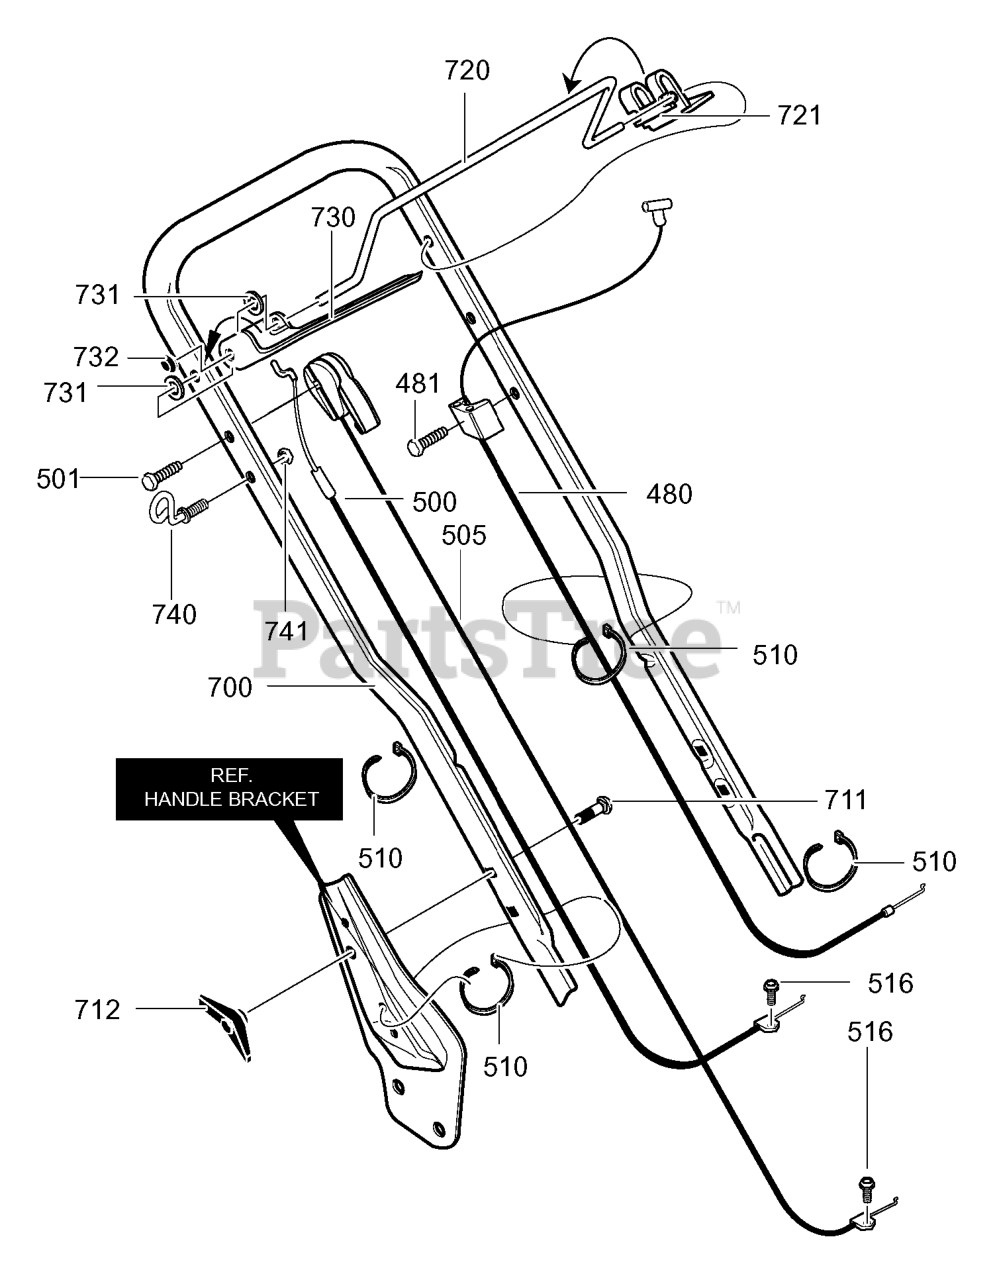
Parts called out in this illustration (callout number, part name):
480	CABLE,STOP
500	CABLE, DRIVE
505	CABLE, SPEED
510	TIE, CABLE BLACK NYLON
712	KNOB, WING
720	LEVER, ENG. WIRE STOP
721	BRACKET, STOP LEVER
730	LEVER, DRIVE CONTROL
731	WASHER
732	CAP, PUSH ON
740	GUIDE, ROPE 1/4-20
741	NUT, 1/4-20
